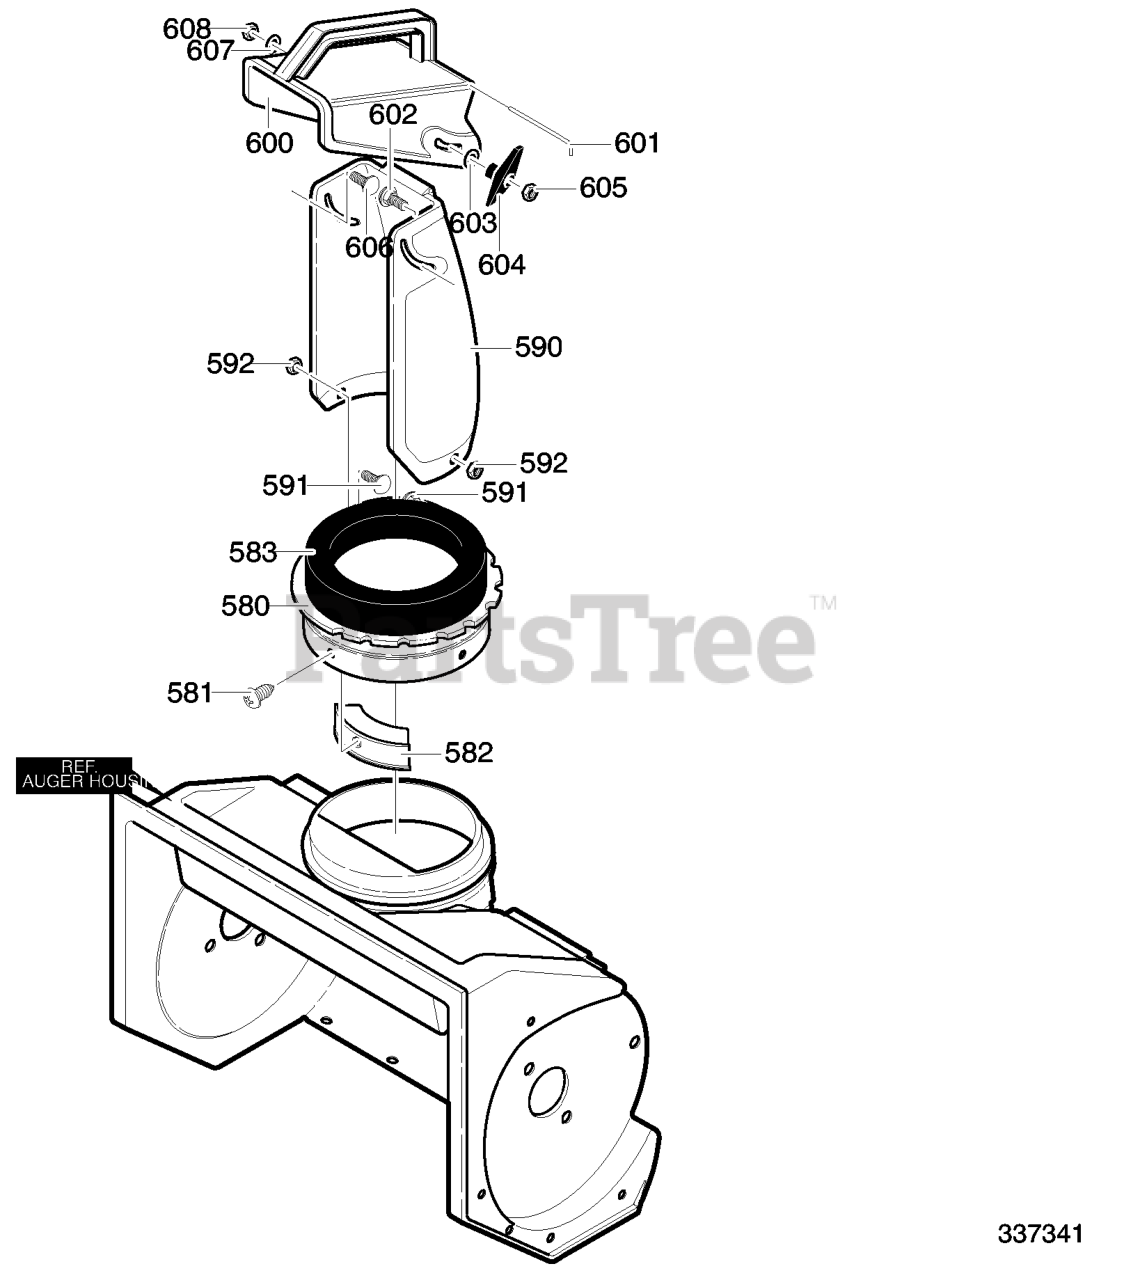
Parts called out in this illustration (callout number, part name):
580	RING, CHUTE
581	SCREW, #10X.50
582	GUIDE, CHUTE
583	DONUT FOAM
590	CHUTE ASSY.
591	SCREW 1/4-20X.50
592	NUT, 1/4-20
601	WIRE, CHUTE HINGE
602	BOLT, 5/16-18X1.25 CARR.
603	WASHER, FLAT .349X.69X.066
604	KNOB, T
605	NUT, 5/16-18
606	SCREW, 5/16-18 x 0.75
607	WASHER, FLAT .349X.69X.066
608	NUT, 5/16-18
